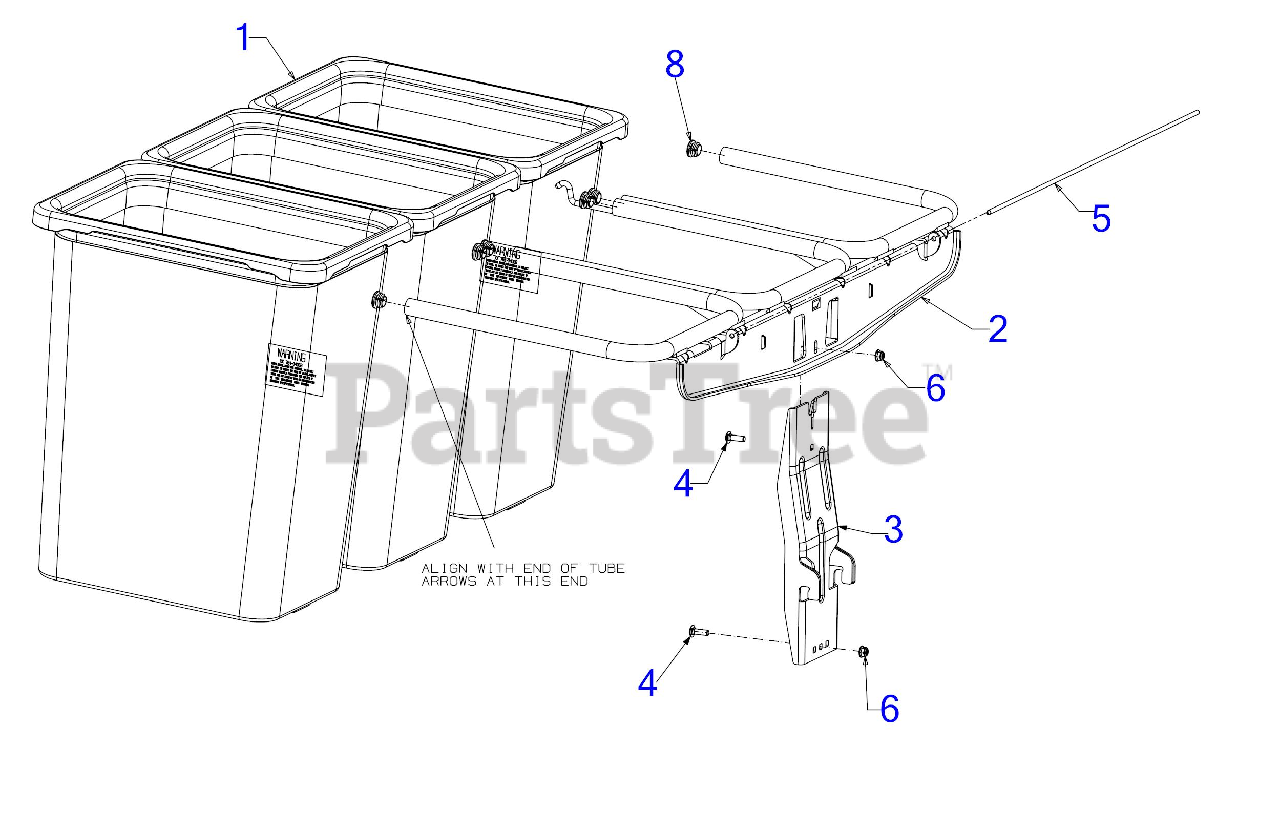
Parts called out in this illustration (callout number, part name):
1	GRASSBAG ASSEMBLY
2	SUPPORT ASSEMBLY
3	VERTICAL SUPPORT BRACKET
4	CARRIAGE BOLT 5/16-18 x 1.00
6	FLANGE LOCK NUT 5/16-18
